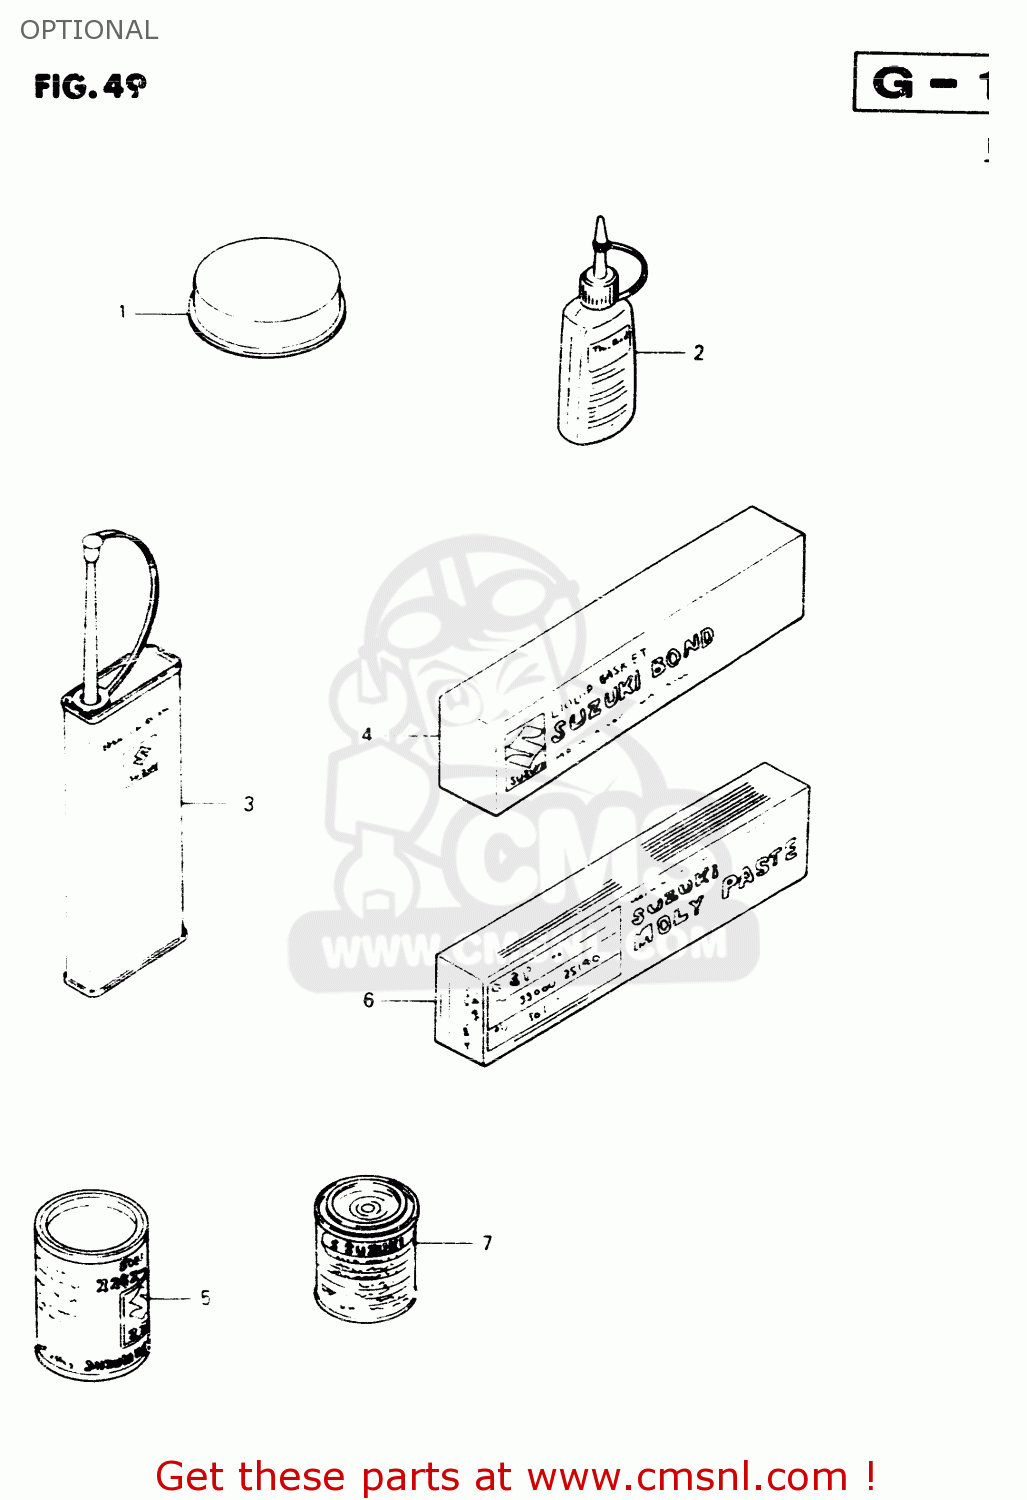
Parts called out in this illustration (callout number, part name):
1	GREASE,PBC FOR BRK PAD 20G
2	THREAD LOCK NO.1342
3	THREAD LOCK NO.1401 CLEAR 200G
4	LIQUID GSKT NO.1215 250G
5	GREASE(C)EP2 LITHIUM 150G
6	SUZUKI MOLY PASTE
7	PAINT,BLACK
